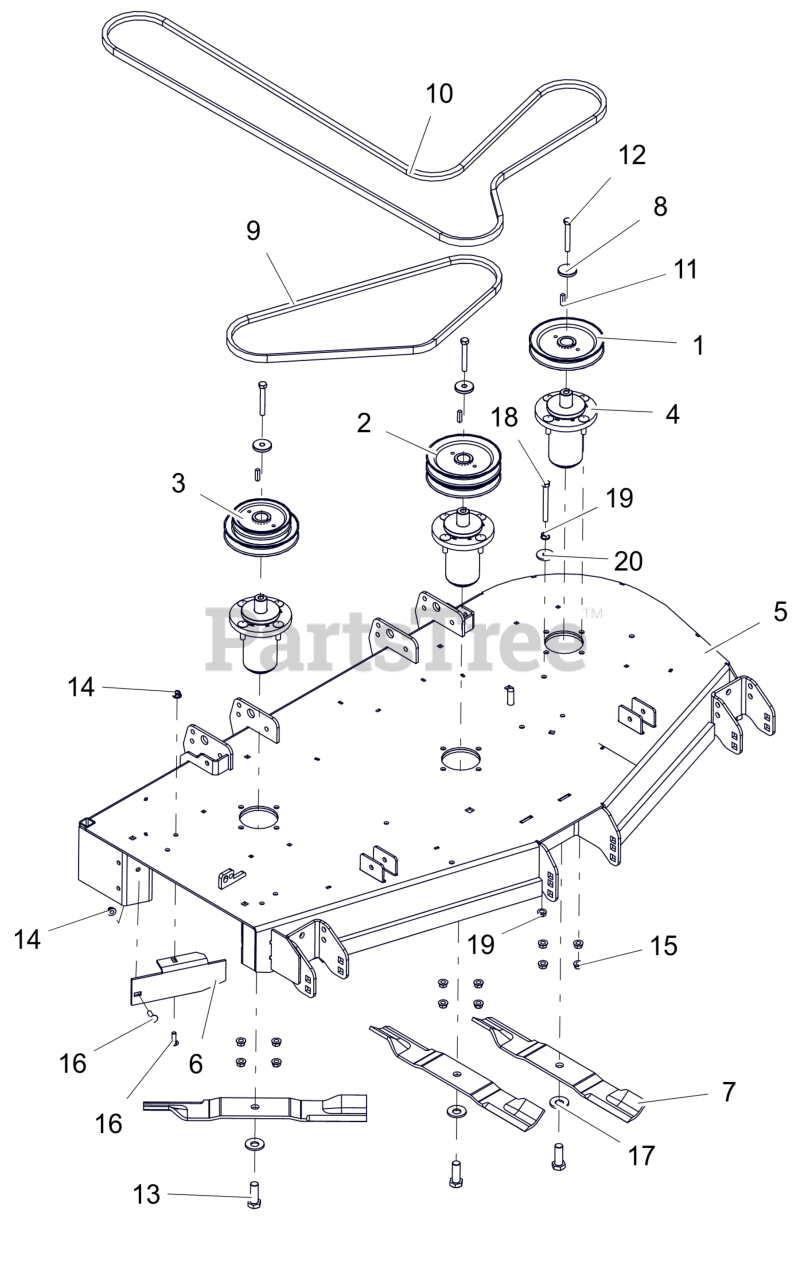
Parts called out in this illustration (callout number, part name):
1	PULLEY, SINGLE -1.000 ID X 6.000 OD
2	PULLEY, DOUBLE 1.000 ID X 6.000 OD
3	PULLEY, DBL-1"IDX6.00"&4.75"OD
4	ASM, MAINT FREE ALUM SPINDLE
5	WLDMT, PT152 SIDE DISCH DECK (RED)
6	52" DISCHARGE BAFFLE - RED
7	BLADE, 18.00" MOWER (HI-LIFT)
8	RETAINER, SHEAVE
9	V-BELT, B-COGGED
10	BELT, B-SECTI0N EPDM RAW EDGE
11	KEY, SQ .25X.25X1.00 RC 40-50
12	BLT, HEX .38-16X2.75 G8 ZCC
13	BLT, HEX .62-18X1.75 G8 ZCC
14	NUT,NYL-FLG .31-18 GF ZCC
15	NUT-LK-CTR-FLG .375-16 GF ZCC
16	BLT,RHSN .31-18X1.00 G5 ZCC
17	WSHR-BLVL .669X1.535X.138
18	BLT, HEX .38-16X3.50 G5 ZCC
19	NUT, SPNLK-FLG .38-16 G5 ZCC
20	WSHR,FLT .406X1.375X.135 ZCC
